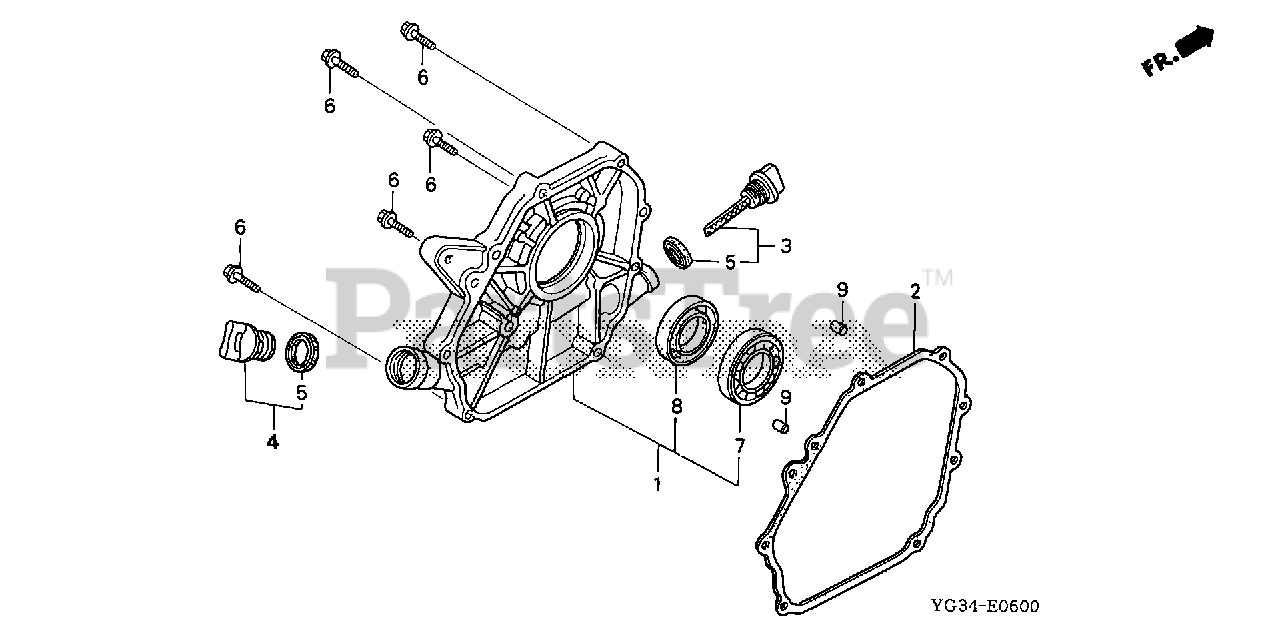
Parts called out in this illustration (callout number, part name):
1	COVER ASSY., CRANKCASE
2	GASKET, CASE COVER
3	CAP ASSY., OIL FILLER (GAUGE)(GRAY)
4	CAP ASSY., OIL FILLER (BLACK)
5	GASKET, OIL FILLER CAP
6	BOLT, FLANGE (6X28) (CT200)
7	BEARING, RADIAL BALL
8	OIL SEAL (22X41X6)
9	PIN, DOWEL (8X14)
